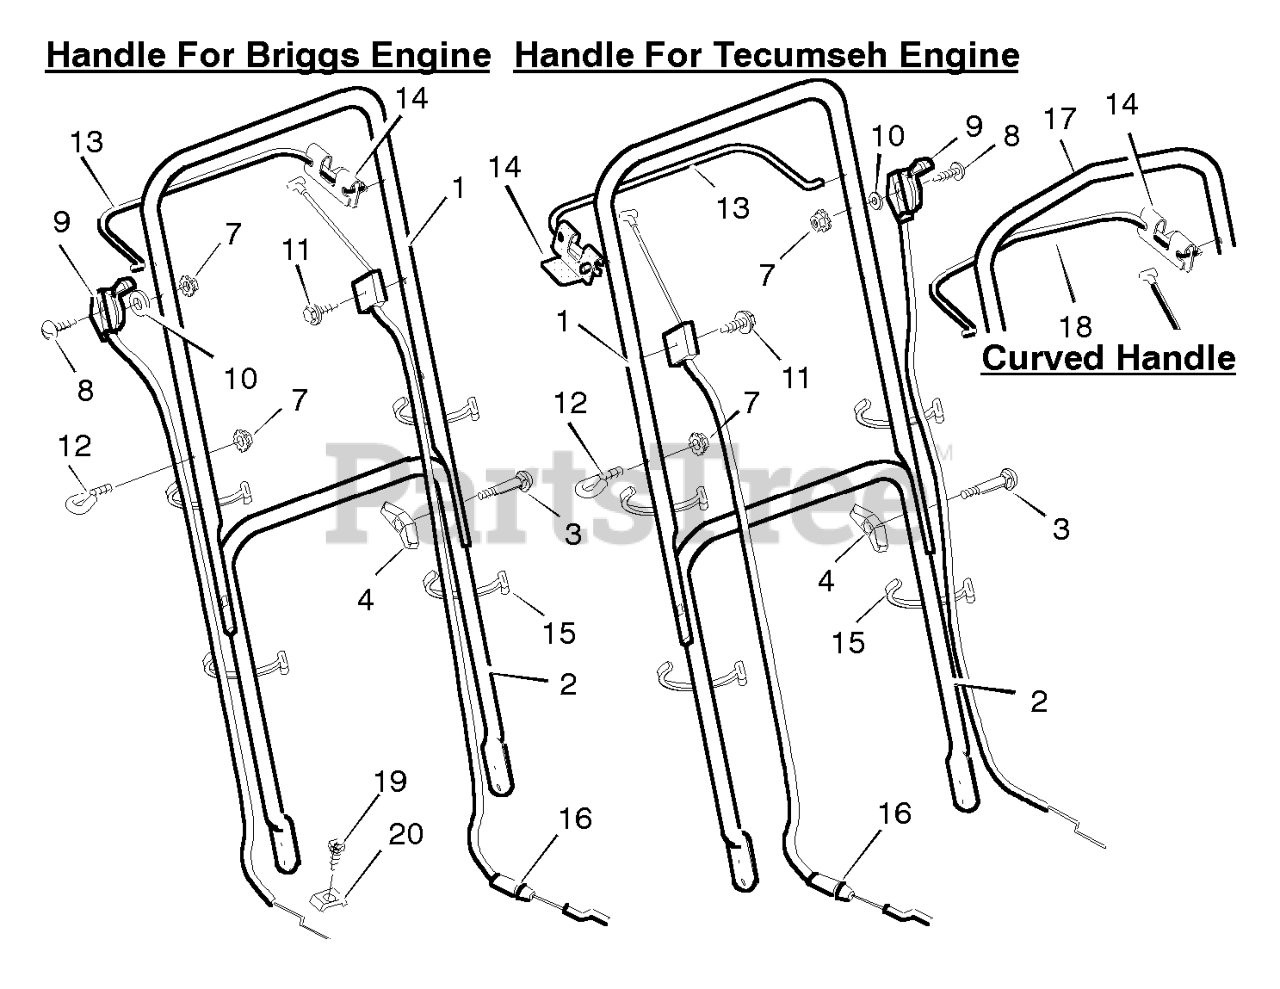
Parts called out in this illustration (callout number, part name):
1	Handle, Upper-Straight (Black)
2	Handle, Lower (Black)
4	Knob, Plastic
7	Locknut
9	Throttle Control
10	Washer
12	GUIDE, ROPE
13	Engine Stop Lever-Straight
14	Bracket, Stop Lever
15	Fastener, Cable
16	Engine Stop Cable *
17	Handle, Upper-Curved (Black)
18	Engine Stop Lever-Curved
19	Screw *
20	Clamp
